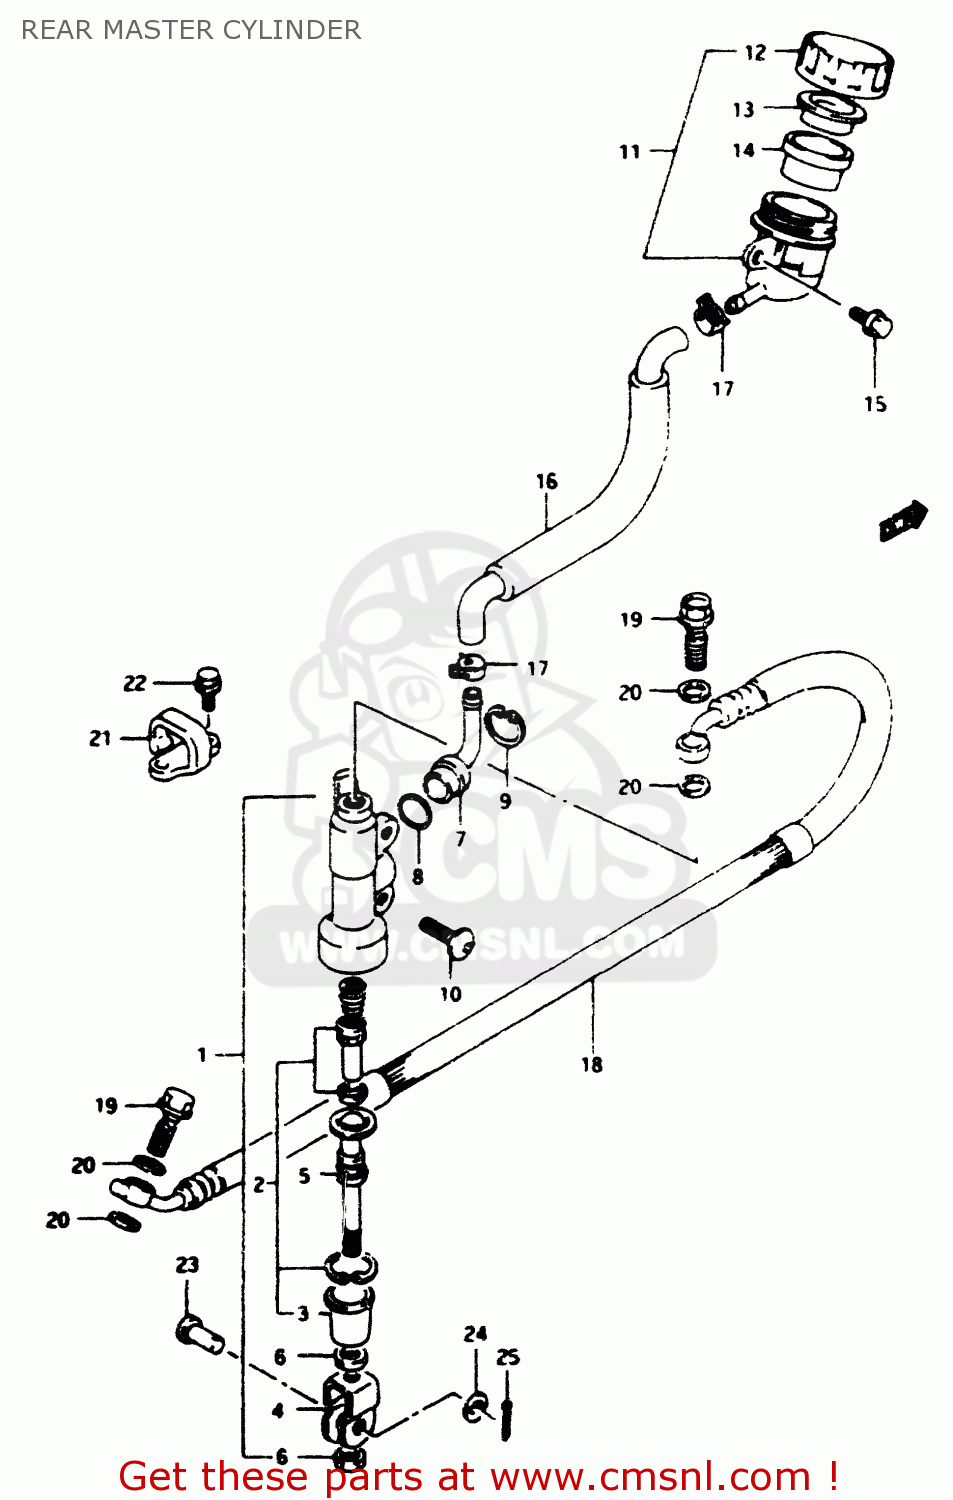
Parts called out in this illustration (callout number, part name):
1	CYLINDER ASSY,RR MASTER
2	PISTON/CUP SET
3	BOOT
4	YOKE
5	ROD,PUSH
6	NUT
7	CONNECTOR
8	O RING
9	CIRCLIP
10	SCREW(6X16)
11	TANK ASSY,RR BRAKE RESERVOIR
12	CAP
13	PLATE
14	DIAPHRAGM
15	BOLT
16	HOSE,RESERVOIR TANK
17	CLAMP,RESERVOIR HOSE
18	HOSE,RR BRAKE
19	BOLT UNION
20	WASHER(10X15X1.5)
21	GUIDE,RR BRAKE HOSE
22	SCREW
23	PIN(8X20)
24	WASHER(8.5X13X1.6)
25	PIN
